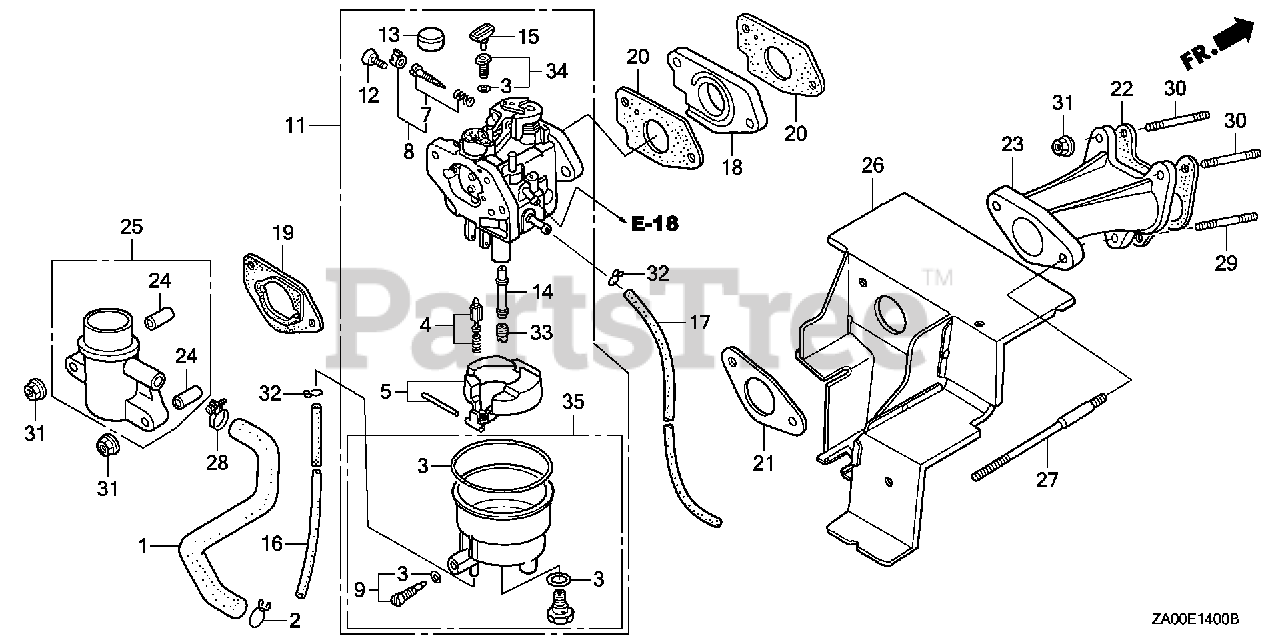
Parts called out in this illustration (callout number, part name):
1	TUBE, BREATHER
2	CLIP, BREATHER TUBE
3	GASKET SET
4	VALVE SET, FLOAT
6	CHAMBER SET, FLOAT
7	SCREW SET, PILOT (CARBURETOR NO.)
8	SCREW SET, PILOT (CARBURETOR NO.)
9	SCREW SET, DRAIN
10	SCREW SET
11	CARBURETOR ASSY. (BE27B C/D)
11	CARBURETOR ASSY. (BE27B E)
12	SCREW, THROTTLE STOP
13	CAP, CHOKE DUST
14	NOZZLE, MAIN
15	COLLAR, SETTING
16	TUBE, FUEL DRAIN
17	TUBE, AIR VENT
18	INSULATOR, CARBURETOR
19	SPACER, CARBURETOR
20	GASKET, CARBURETOR
21	GASKET, INSULATOR
22	GASKET, IN. MANIFOLD
23	MANIFOLD, IN.
24	COLLAR, AIR CLEANER
25	ELBOW, AIR CLEANER
26	COVER ASSY., EX.
27	BOLT, STUD (8X123)
28	CLIP A18, TUBE
29	BOLT, STUD (6X32)
30	BOLT, STUD (6X40)
30	BOLT, STUD (6X28)
31	NUT, FLANGE (6MM)
32	CLIP, TUBE (B8)
33	JET, MAIN (#82)
33	JET, MAIN (#85)
33	JET, MAIN (#88)
34	JET SET, PILOT (#45)
35	BOLT KIT, FUEL CHAMBER
